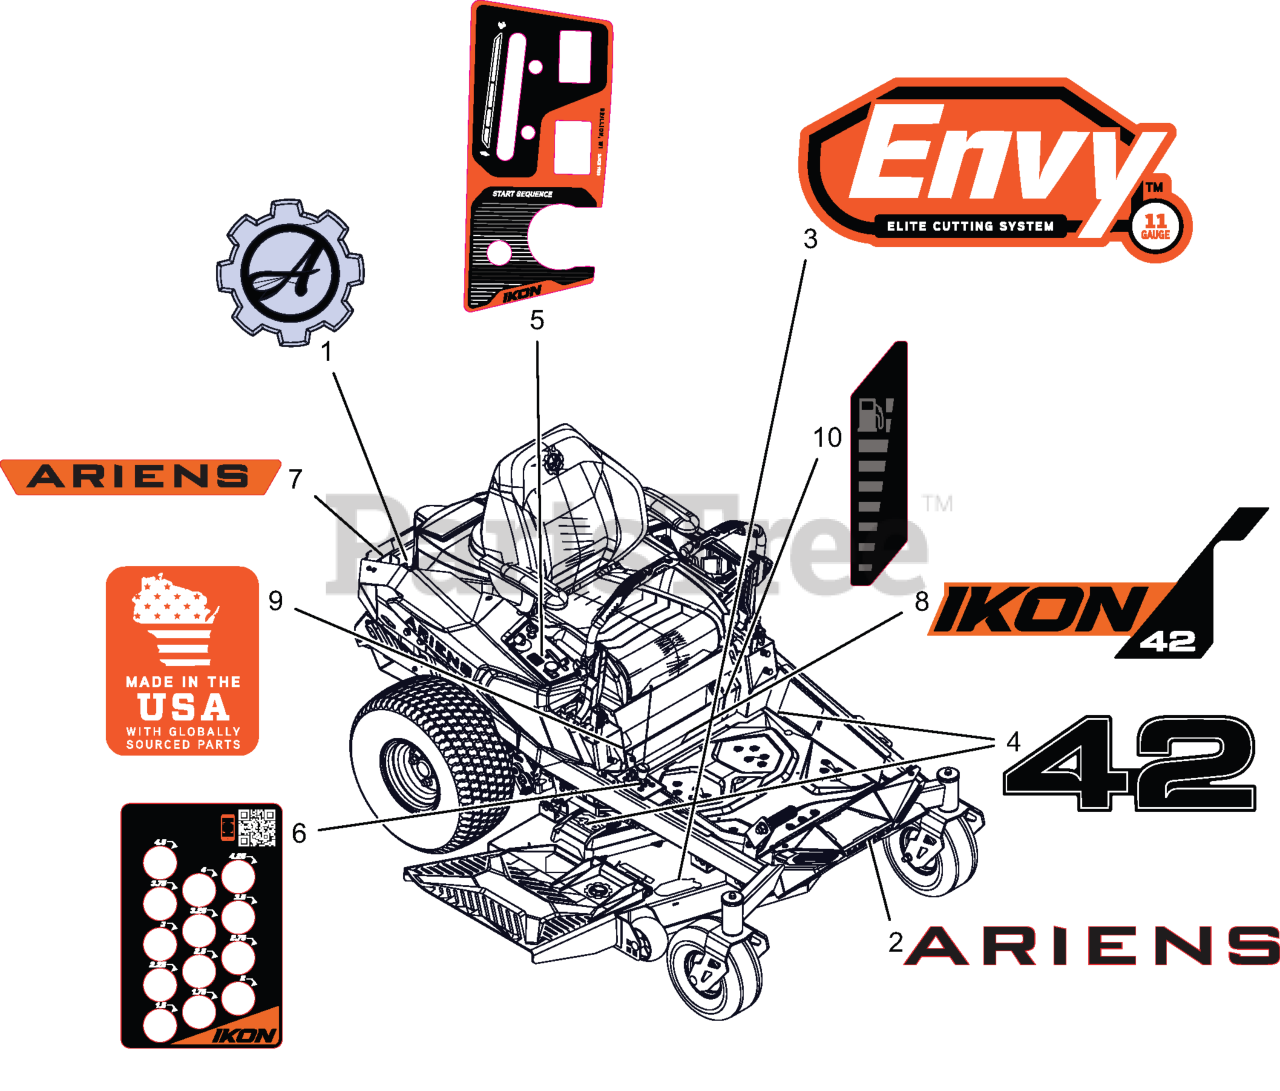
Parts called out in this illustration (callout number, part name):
1	DECAL- ARIENS GEAR BADGE
2	DECAL- ARIENS-BADGE
3	DECAL- DECK
4	DECAL- 42
5	DECAL- CONTROL PANEL
6	DECAL- HEIGHT OF CUT
7	DECAL- ARIENS
8	DECAL- IKON 42 KICKPLATE
9	DECAL- MADE IN USA
10	DECAL, FUEL LEVEL
